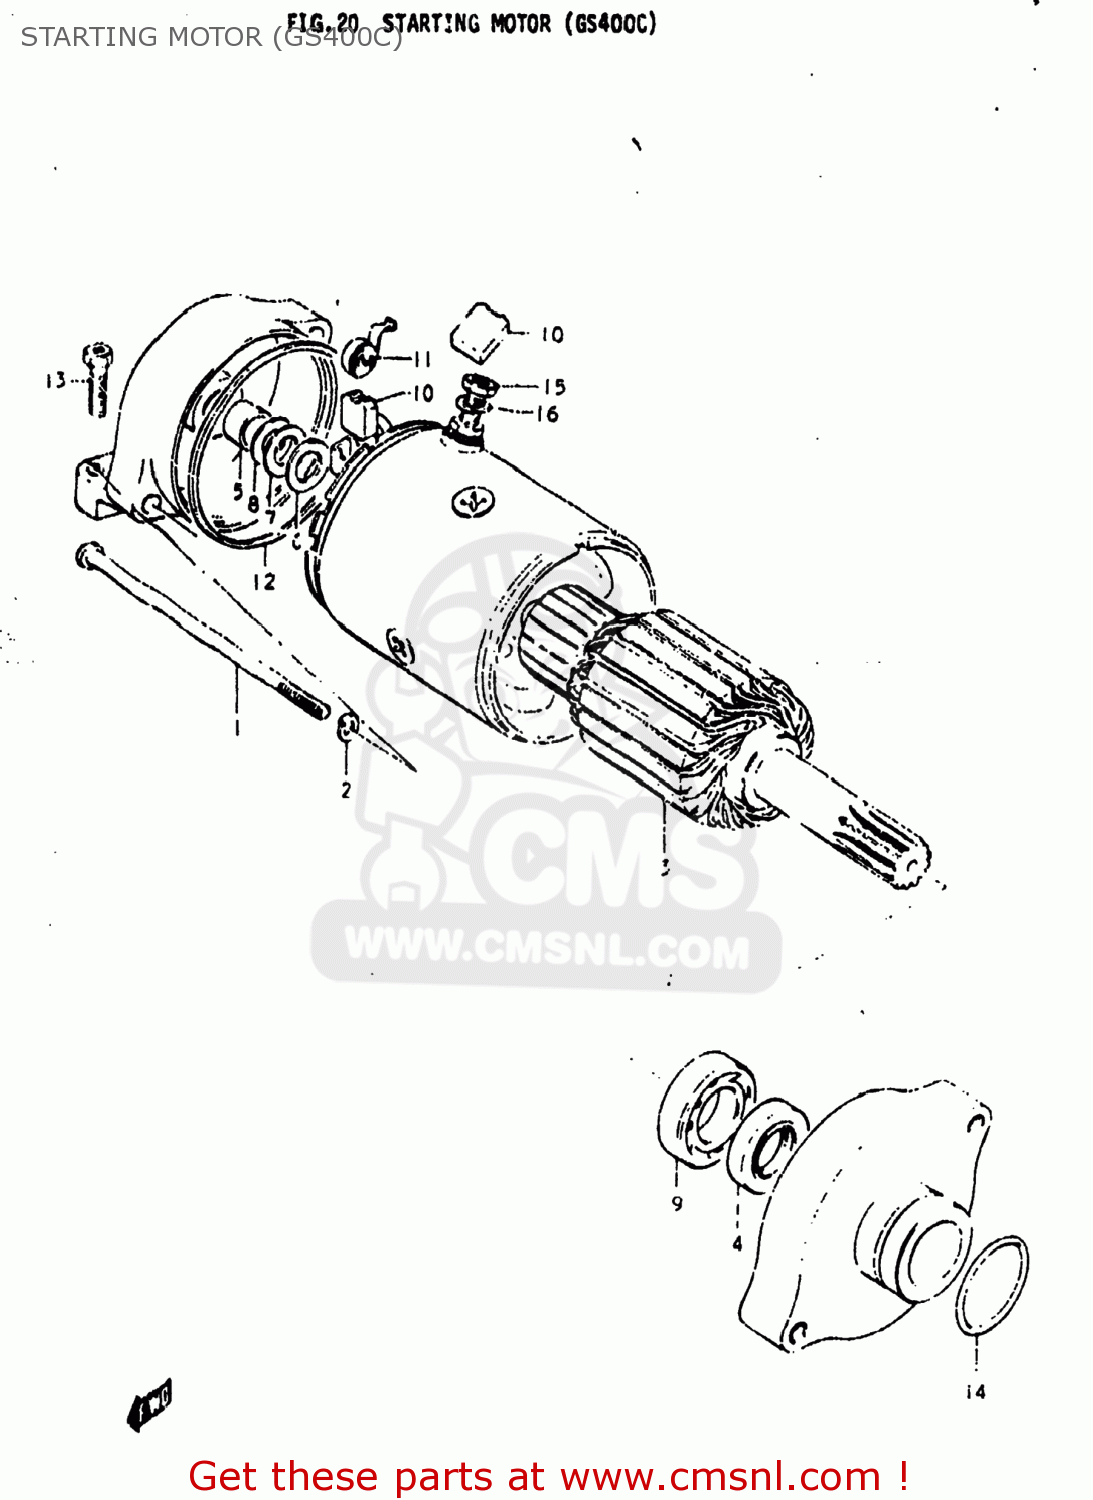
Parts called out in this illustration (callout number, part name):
1	BOLT
2	LOCK WASHER
3	ARMATURE
4	SEAL,OIL
5	BUSHING
6	SHIM, (1)
7	SHIM, (2)
8	SHIM, (3)
9	BEARING
10	BRUSH(-)
11	SPRING
12	GASKET
13	SCREW
14	O RING(D:2,ID:24.5)
15	NUT 6MM
16	LOCK WASHER
